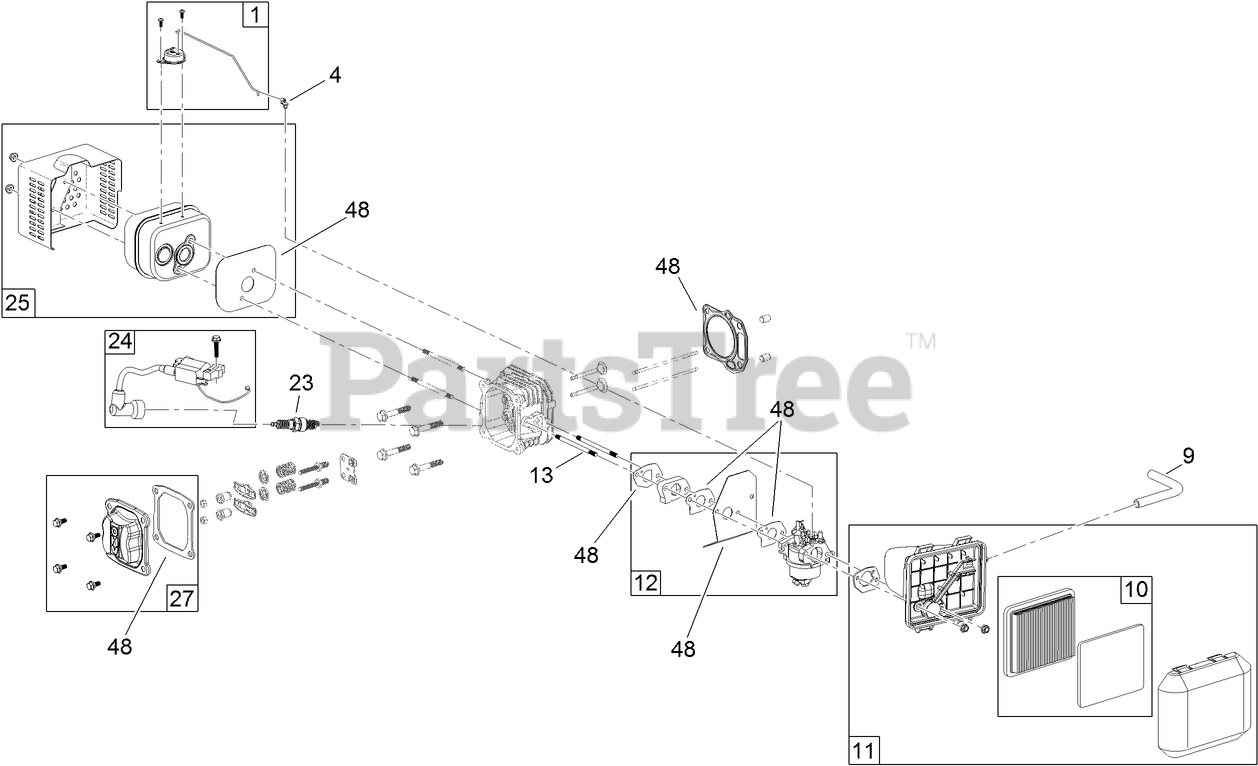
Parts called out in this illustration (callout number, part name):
1	THERMAL CHOKE CONTROL KIT
4	LOCK-THROTTLE
9	TUBE-BREATHER
10	AIR FILTER AND PREFILTER KIT
11	AIR CLEANER ASM
12	CARBURETOR COMPLETE KIT
13	STUD-INTAKE
23	SPARK PLUG
24	IGNITION AND HARDWARE KIT
27	VALVE COVER KIT
48	SEAL AND GASKET KIT
